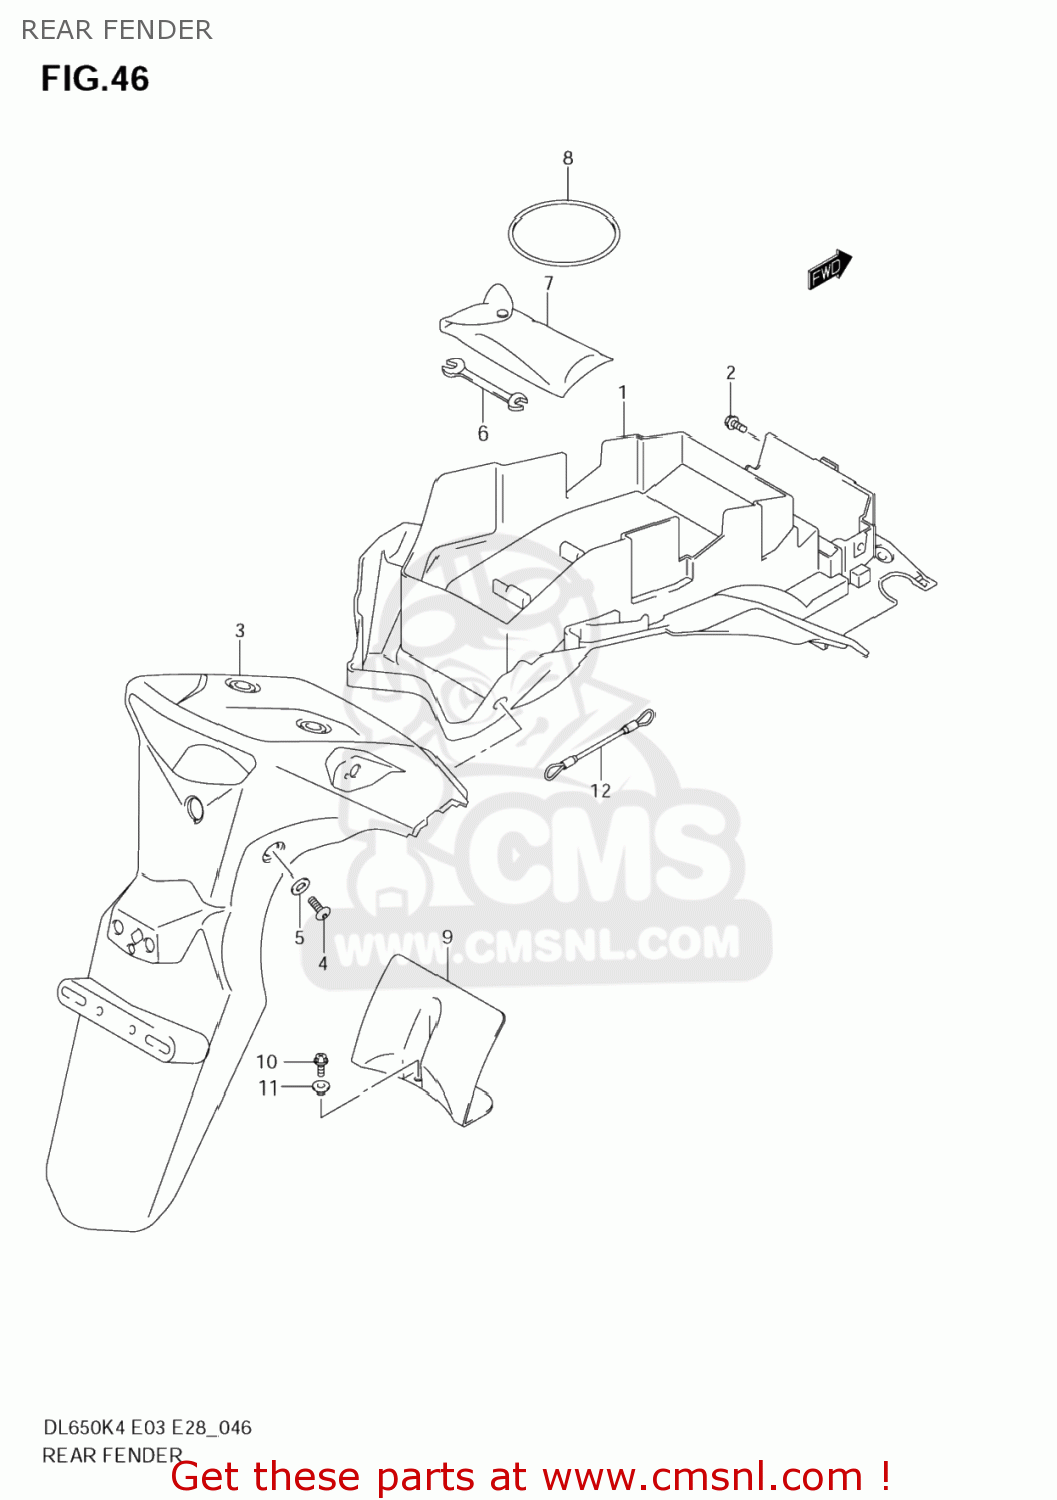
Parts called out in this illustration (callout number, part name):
1	FENDER,RR FR
2	BOLT 6X14
3	FENDER, REAR (BLACK)
4	SCREW(6X16)
5	WASHER(6.5X18X1.6)
6	OPEN SPANNER(8X10)
7	TOOL ASSY
8	O RING(D:3.5,ID:61)
9	MUDGUARD,RR FENDER FR LWR
10	SCREW
11	WASHER
12	CABLE,HELMET LOCK
